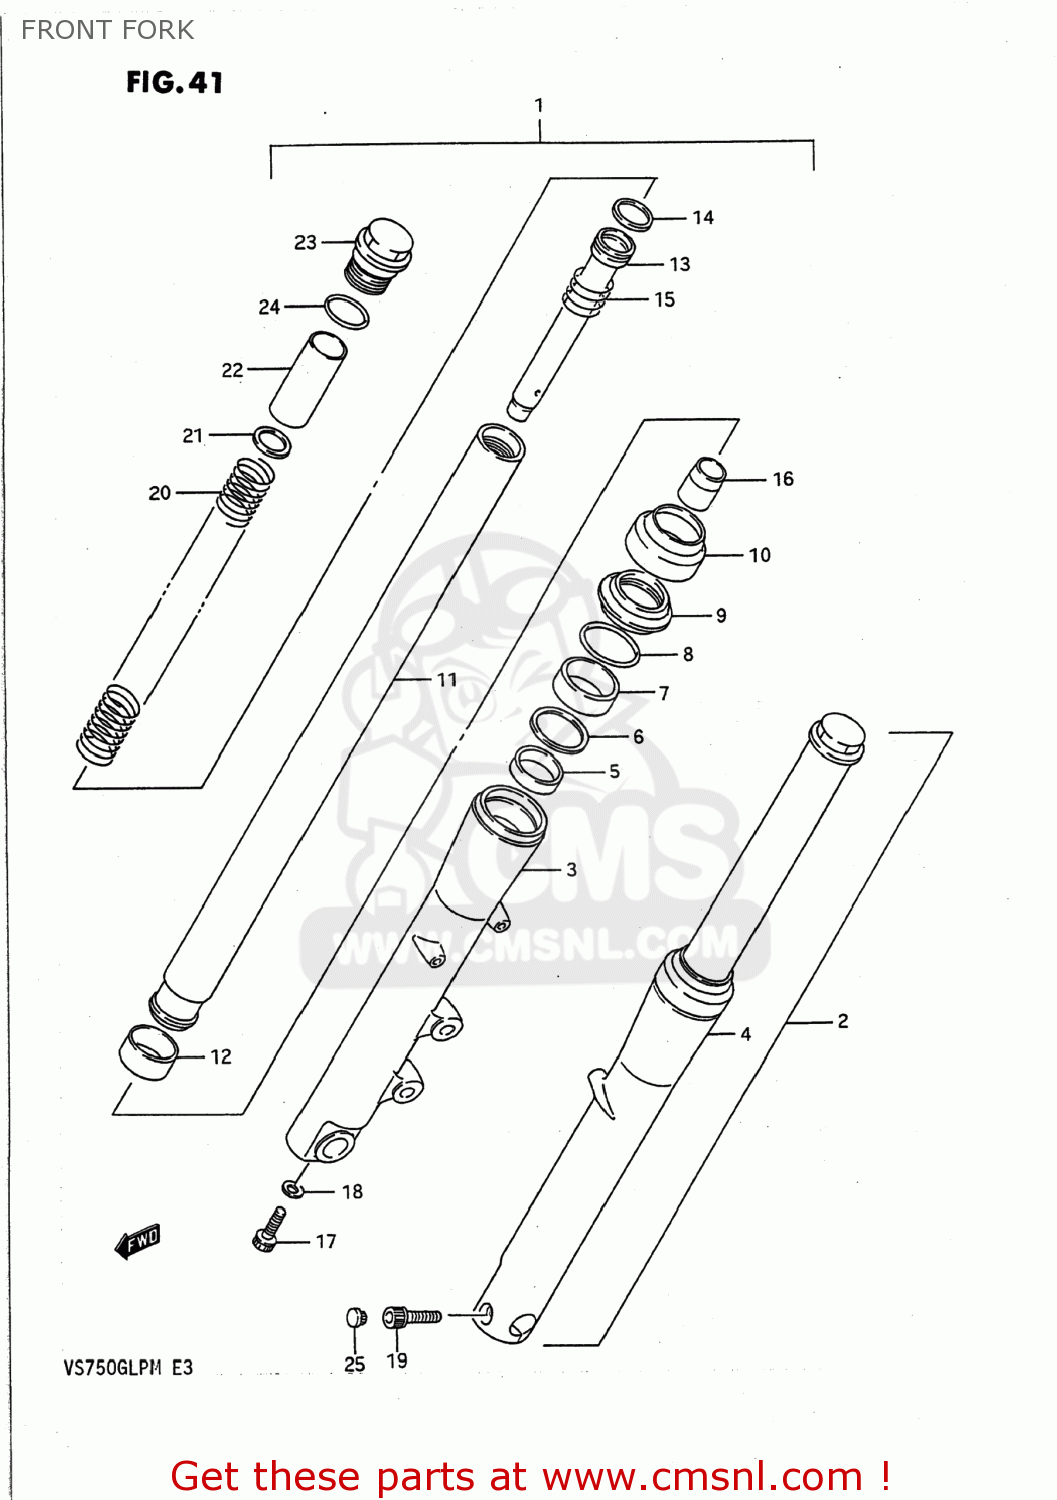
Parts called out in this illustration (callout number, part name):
1	DAMPER ASSEMBLY,RIGHT
2	DAMPER ASSEMBLY,LEFT
3	TUBE,OUTER RH
4	TUBE,OUTER LH
5	BUSHING,GUIDE
6	SPACER,SEAL
7	OIL SEAL,FRONT FORK
8	CUSHION,HEADLAMP BRACKET
9	BOOT
10	BAND,FRONT FORK COVER
11	TUBE,FORK,INNER
12	BUSHING,SLIDE
13	PIPE,SEAT
14	RING,PISTON
15	SPRING,REBOUND
16	PIECE,OIL LOCK
17	BOLT(8X27)
18	GASKET (NAS)
19	BOLT, FRONT RH
20	SPRING
21	WASHER,SPRING
22	COLLAR,SPRING
23	BOLT,FORK
24	O RING
25	CAP(OD:14.5)
